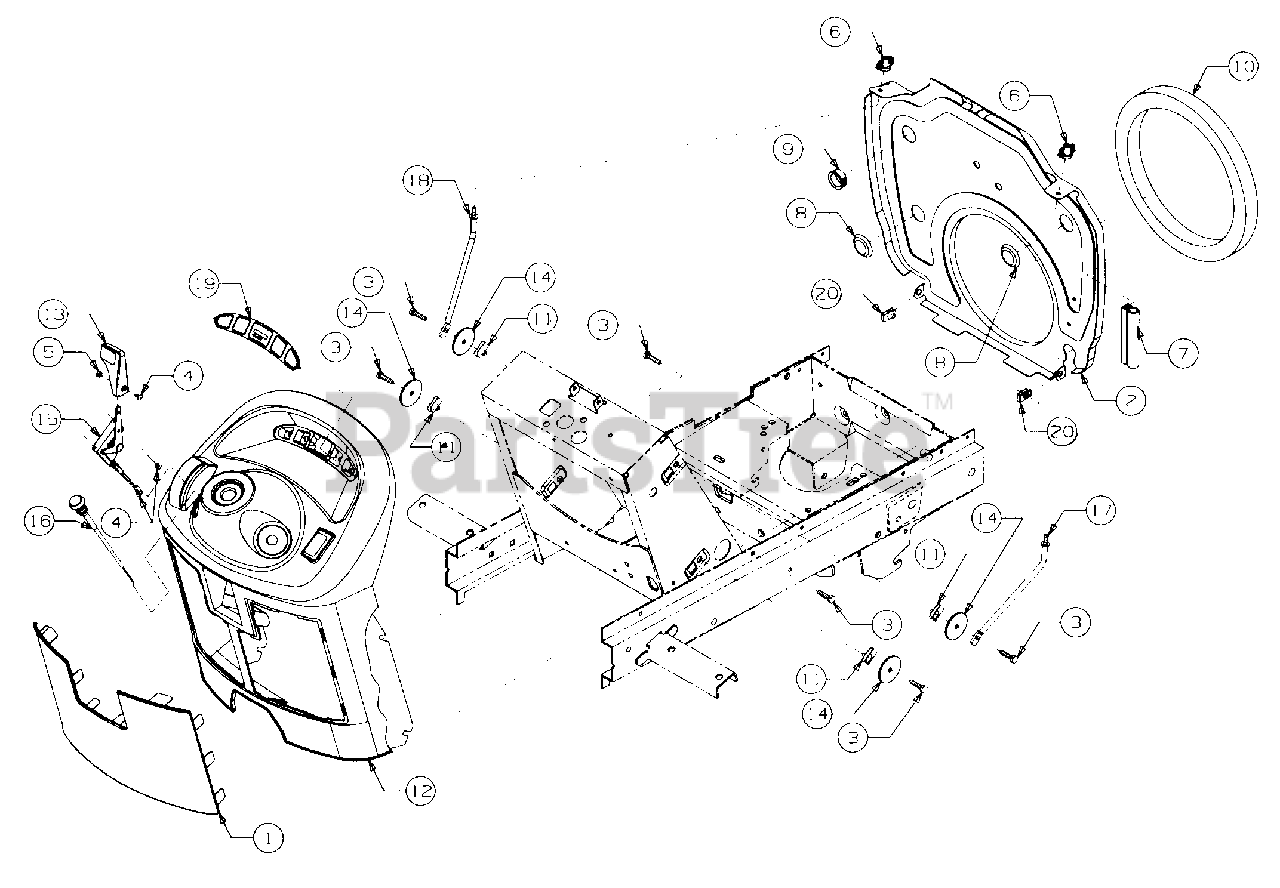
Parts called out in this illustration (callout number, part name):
2	Bulkhead, Lower
3	Screw, Hex Cap, 1/4-20 x 1.0 Lg GR2
4	Screw, Cross Rec Truss #8-32 X.38 Lg Hd
5	Nut, #8-32
6	Nut, Wing w/Bell Washer, 1/4-20
8	Plug, Button, 1.12 Dia
9	Bushing, Snap, 7/8 ID
10	Ring, Foam Sealing
11	Nut, U-Clip, 1/4-20
12	Panel, Dash
13	Knob, Throttle
14	Washer, Flat, .285 x 1.75 x .10 Thk
15	Control, Throttle
16	Control, Choke
17	Rod, RH Mounting
18	Rod, LH Mounting
19	Label, Dash
20	Nut, U-Type Speed, 1/4-20
